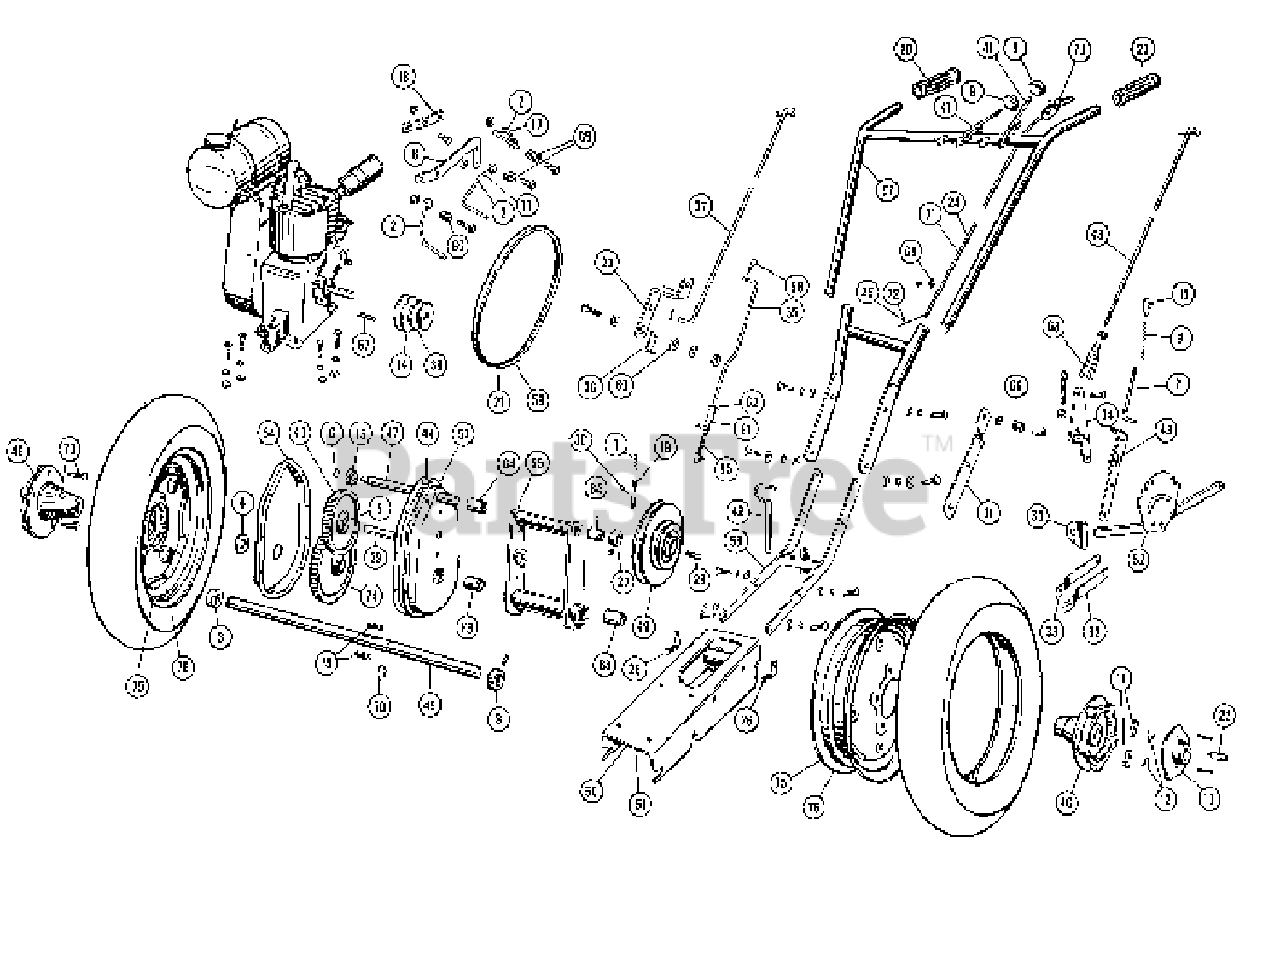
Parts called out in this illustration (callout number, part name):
1	SPRING, Transmission Pulley
2	STOP, Belt
3	COLLAR, Set
5	BUSHING, Intermediate
6	RING, Retaining
8	HOLDER, Belt Stop
9	BALL, Clutch Lever
10	KNOB, Plunger
11	DOG, Ratchet
12	SPRING, Ratchet
13	CAGE, Ratchet
14	PULLEY, Engine (3 Hp Only)
15	PINION, Reduction
16	KEY, Axle
17	STOP, Belt (3 HP Only)
18	BRACKET, Belt Holder (3 HP Only)
19	PIN, Transmission Pulley
20	GRIP, Rubber
21	BELT, 39", Transmission (3 HP Only)
22	KEY (Ratchet Cage)
23	LEVER, Lower Clutch
24	CABLE, Throttle (3 HP only)
25	WIRE, Throttle (3 HP only)
26	CLAMP, Bearing
27	COLLAR, Set (Pulley Shaft)
28	KEY, Transmission Pulley
29	SPINDLE, Intermediate
30	GUIDE, Shaft
31	EXTENSION, Frame
32	LINK, Throw-Out
33	LINK, Tapped, Throw-Out
34	LEVER, Lower Clutch
35	ROD, Lower Idler
36	STOP, Lever
37	ROD, Upper Idler
38	PULLEY, Engine (2 HP Only)
39	PIN, Transmission Sheave Spring
40	GEAR ASSEMBLY, Cluster
41	LEVER ASSEMBLY, Clutch
42	PIN ASSEMBLY, Draw Bar
43	LEVER ASSEMBLY, Shift
44	GASKET, Gear Case
46	HUB, Wheel
47	SHAFT, Pulley
48	ROD, Clutch
49	PULLEY ASSEMBLY, Transmission
50	BASE ASSEMBLY, 2 HP Only
51	BASE ASSEMBLY, 3 HP Only
52	THROW-OUT ASSEMBLY
53	CASE, Gear
54	COVER, Gear Case
55	HOUSING ASSEMBLY, Bearing
56	FRAME ASSEMBLY
57	HANDLE ASSEMBLY
58	CLIP, Spring
59	BELT, Transmission, 43" (2 HP Only)
61	SOCKET ASSEMBLY
62	COLLAR, Set
63	AXLE, Bushing
64	SHAFT BEARING, Pulley
67	KEY, Engine Pulley
68	END ASSEMBLY, Rod
69	CLAMP, Cable
70	RING, Retaining
71	CABLE, Throttle (2 HP Only)
72	WIRE, Throttle (2 HP Only)
74	GEAR, Drive
75	WHEEL, 4" Rim (2 HP Only)
76	WHEEL, 5" Rim (3 HP Only)
77	LEVER ASSEMBLY, Throttle
